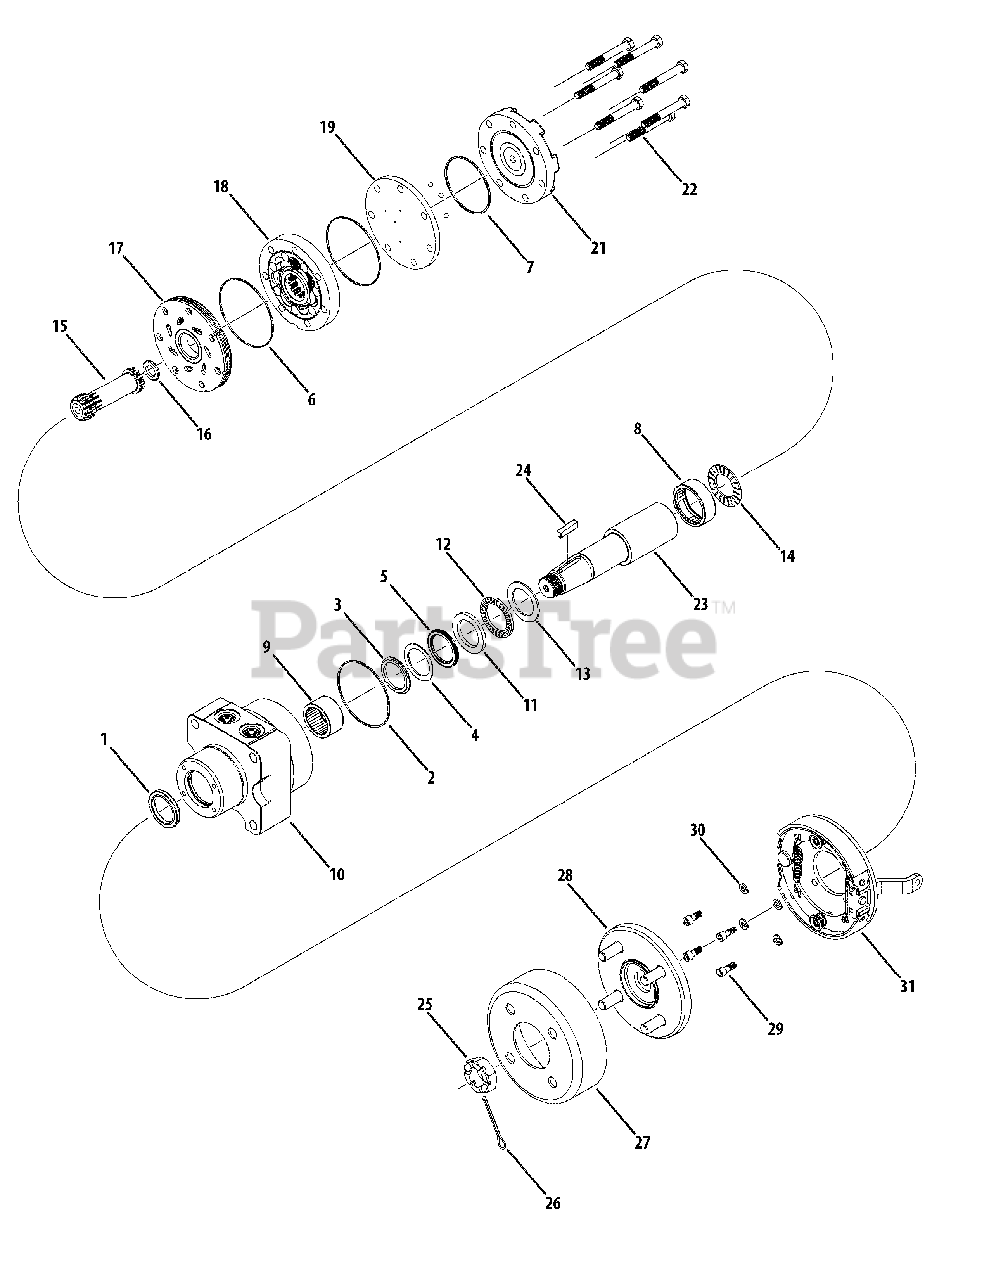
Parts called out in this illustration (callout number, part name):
1	Dust Seal
2	Housing Seal
3	Back Up Ring
4	Back Up Seal
5	Shaft Seal
6	Body Seals
7	Endcover Seal
8	Rear Housing Bearing includes (items 1-7)
9	Front Housing Bearing
11	Front Thrust Washer
12	Front Thrust Bearing
13	Thrust Washer
14	Rear Thrust Bearing
16	Drive Link Spacer
19	Balance Plate
22	Assembly Bolts
27	6" Stamped Drum
28	4-Lug Knott Hub
29	Mounting Bolts
30	Lock Washers
